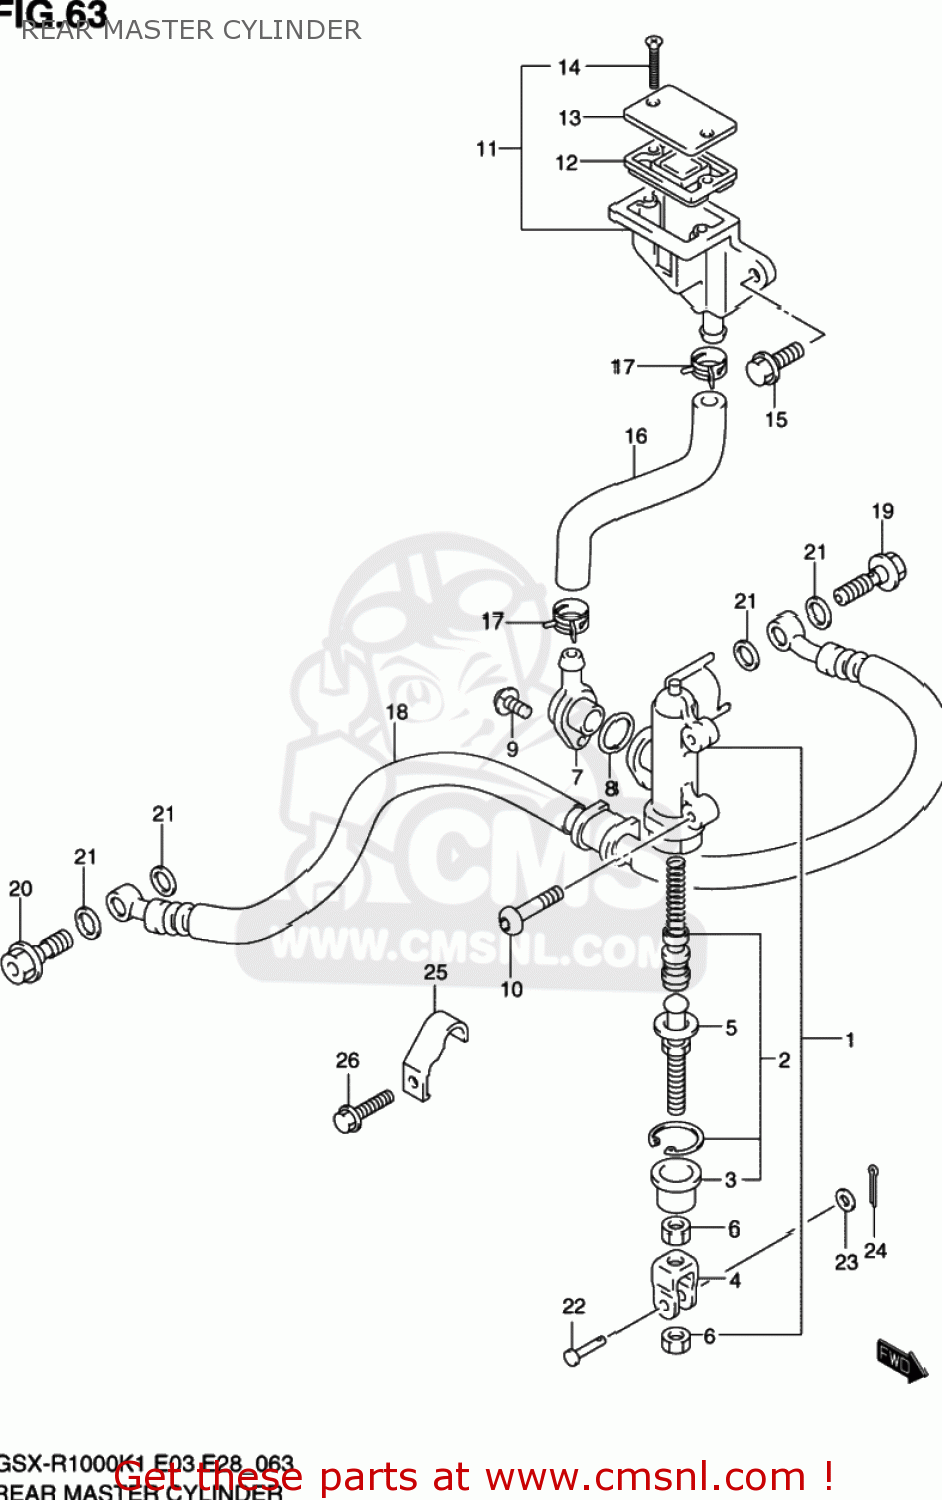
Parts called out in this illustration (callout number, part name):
1	CYLINDER ASSY,RR MASTER
2	PISTON/CUP SET
3	BOOT
4	YOKE
5	ROD,PUSH
6	NUT
7	CONNECTOR
8	O RING
9	SCREW
10	SCREW(6X20)
11	TANK ASSY,RR RESERVOIR
12	DIAPHRAGM
13	CAP
14	SCREW
15	BOLT(6X12)
16	HOSE,RESERVOIR TANK
17	CLIP
18	HOSE,RR BRAKE
19	BOLT UNION
20	BOLT UNION
21	WASHER(10X15X1.5)
22	PIN
23	WASHER
24	PIN
25	CLAMP,RR BRAKE HOSE
26	BOLT(6X20)
